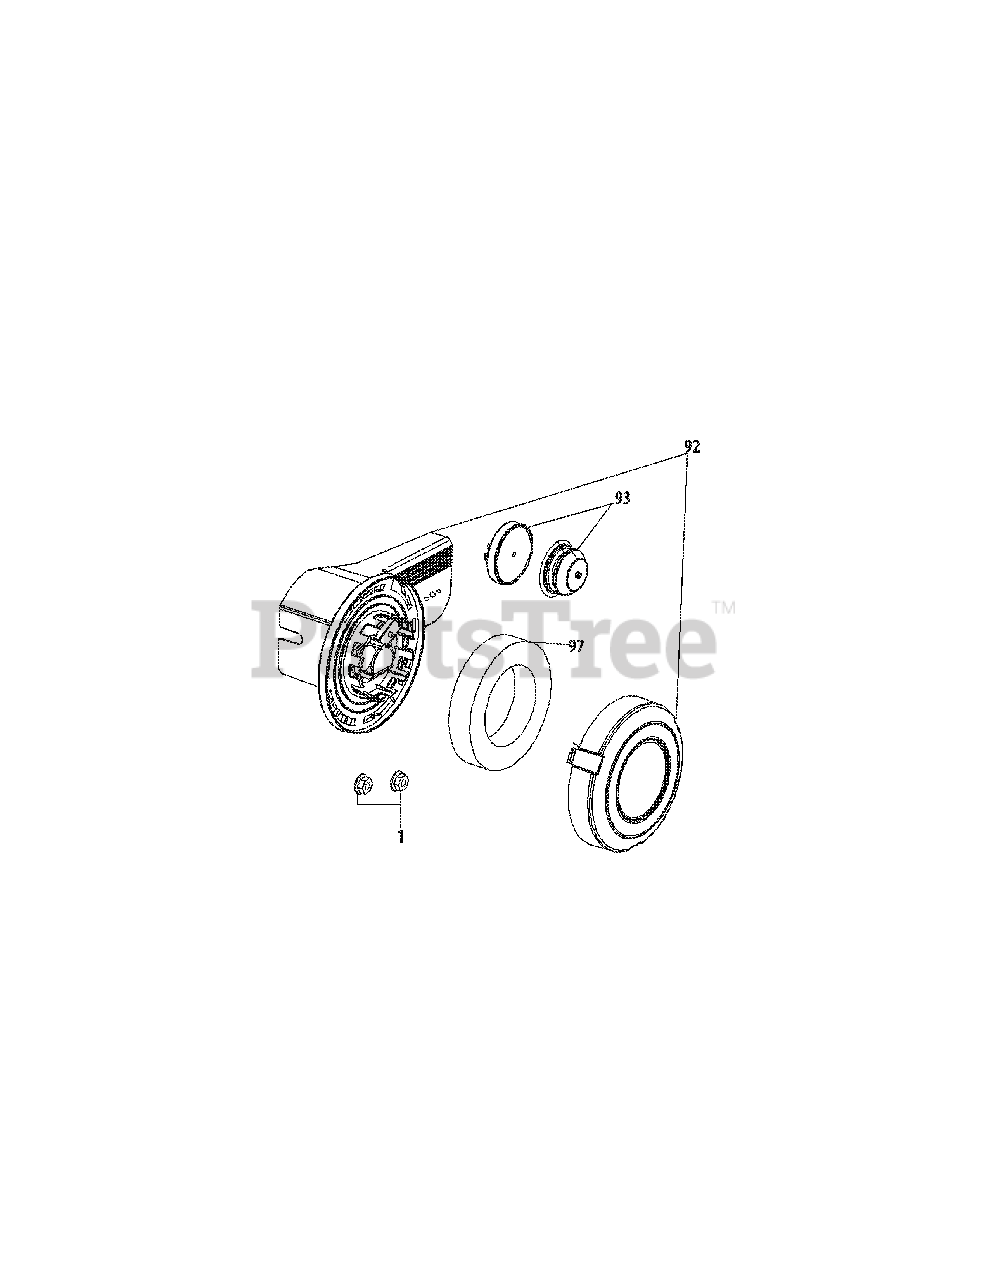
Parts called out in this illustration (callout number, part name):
1	Nut M6X10Mm Starter/Carb/Muff
92	Air Filter Assembly
93	Primer Assembly
97	Air Filter Element, Foam
